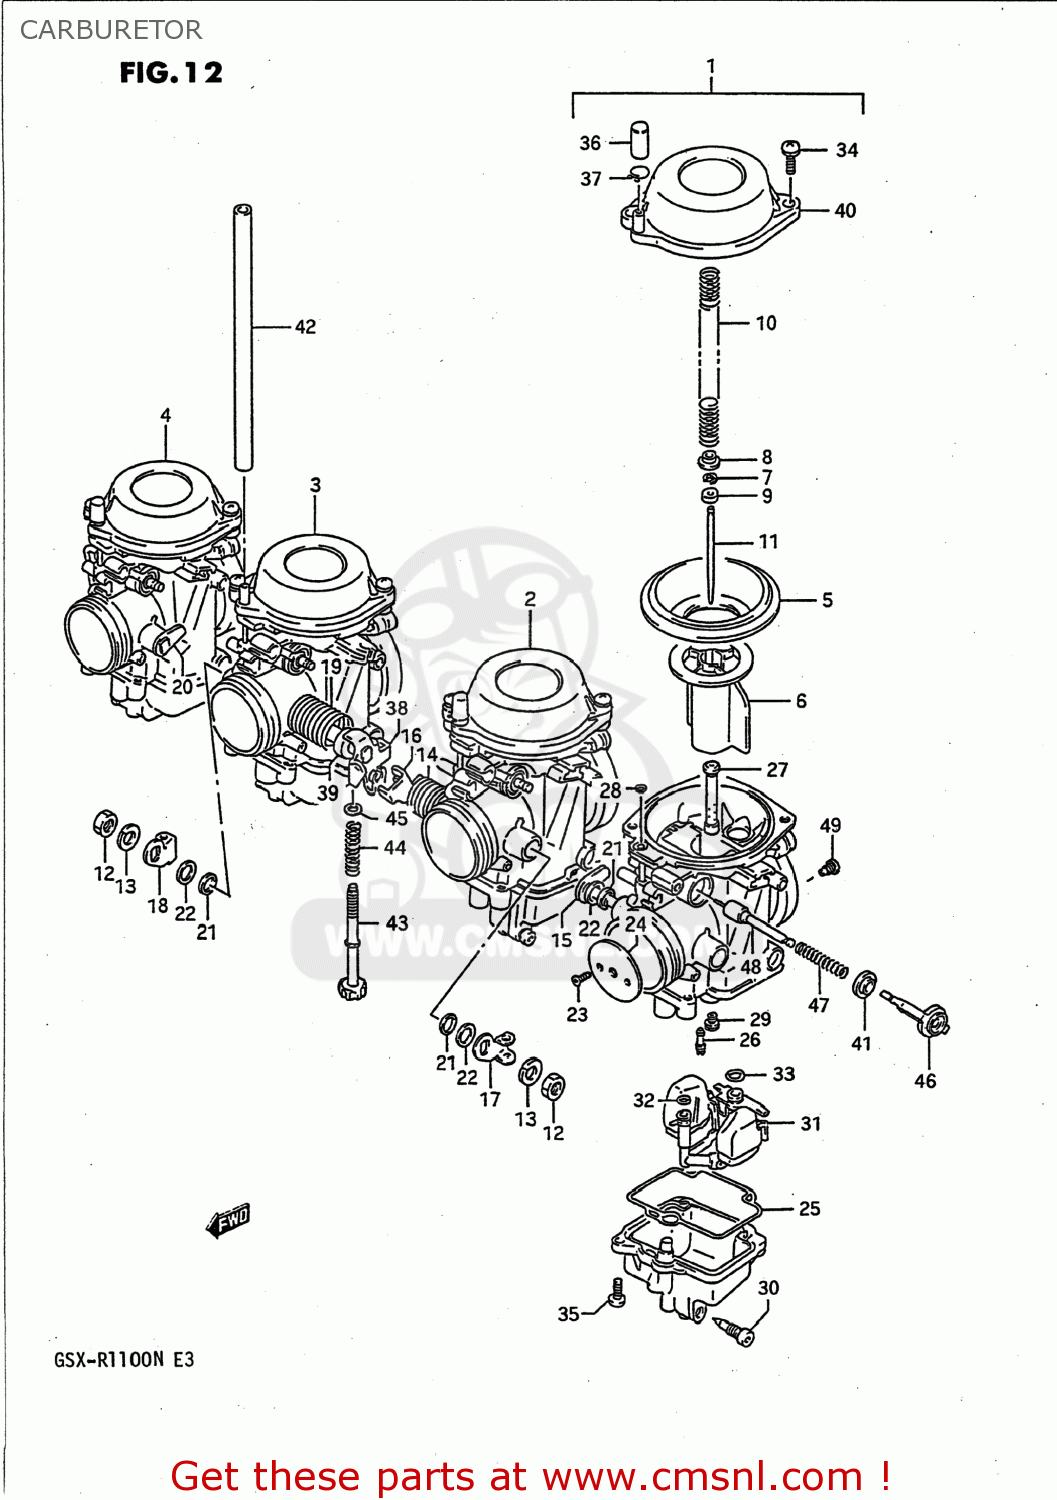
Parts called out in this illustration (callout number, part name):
1	CARBURETOR ASSEMBLY,LEFT
2	CARBURETOR ASSEMBLY,MIDDLE,LEFT
3	CARBURETOR ASSEMBLY,MIDDLE,RIGHT
4	CARBURETOR ASSEMBLY,RIGHT
5	DIAPHRAGM
6	VALVE,PISTON
7	CLIP
8	RING
9	RING
10	SPRING
11	NEEDLE,JET
12	NUT
13	WASHER,LOCK,8.
14	SPRING
15	SHAFT ASSEMBLY
16	SHAFT ASSEMBLY
17	LEVER
18	LEVER,THROTTLE
19	SPRING
20	SHAFT ASSEMBLY
21	SEAL
22	GASKET,THROTTLE SHAFT (NAS)
23	SCREW
24	VALVE,THROTTLE(125)
25	GASKET,FLOAT CHAMBER (NAS)
26	JET,PILOT(30)
27	JET,NEEDLE(O-8)
28	O RING
29	JET,MAIN(122.5)
30	PLUG
31	FLOAT/NEEDLE VALVE ASSY
32	O RING
33	O-RING,NEEDLE VALVE
34	SCREW
35	SCREW
36	CAP
37	CLIP
38	SHAFT ASSEMBLY
39	RING
40	COVER,DIAPHRAGM
41	CAP,STARTER
42	HOSE
43	SCREW
44	SPRING
45	WASHER
46	HOLDER,GUIDE
47	SPRING
48	PLUNGER ASSY
49	JET,AIR(1.2)
